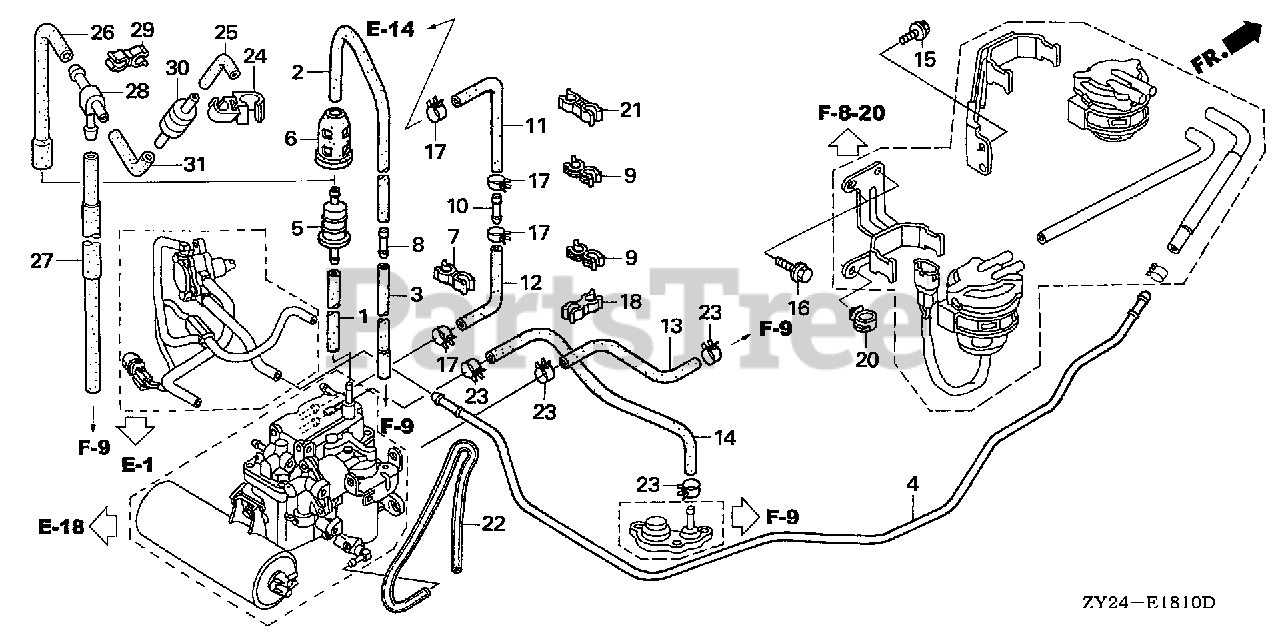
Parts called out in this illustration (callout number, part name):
1	TUBE A, AIR VENT
2	TUBE B, AIR VENT
3	TUBE, AIR VENT
4	PIPE, FUEL
5	FILTER, FUEL PUMP
6	SUSPENSION, STRAINER
7	CLAMP, HOSE
8	JOINT, FUEL TUBE
9	CLIP, TUBE
10	JOINT, FUEL RETURN
11	HOSE A, PRESSURE REGULATOR RETURN
12	HOSE B, PRESSURE REGULATOR RETURN
13	TUBE, WATER INLET
14	TUBE, WATER OUTLET
15	BOLT, FLANGE (6X14)
16	BOLT, FLANGE (6X10)
17	CLAMP, TUBE (D10.7)
18	CLIP, WIRE
20	CLIP, WIRE HARNESS (25MM)
21	CLAMP, FUEL TUBE
22	BULK HOSE, VINYL (3.5X6.5X8000) (3.5X6.5X600)
23	CLAMP, TUBE (D10.5)
24	CLAMP, CHECK VALVE
25	TUBE, CHECK VALVE
26	TUBE B, AIR VENT
27	TUBE, AIR VENT
28	T-JOINT
29	CLAMP, HOSE
30	VALVE, CHECK
31	BULK HOSE, FUEL (3.5X3000) (3.5X55)
